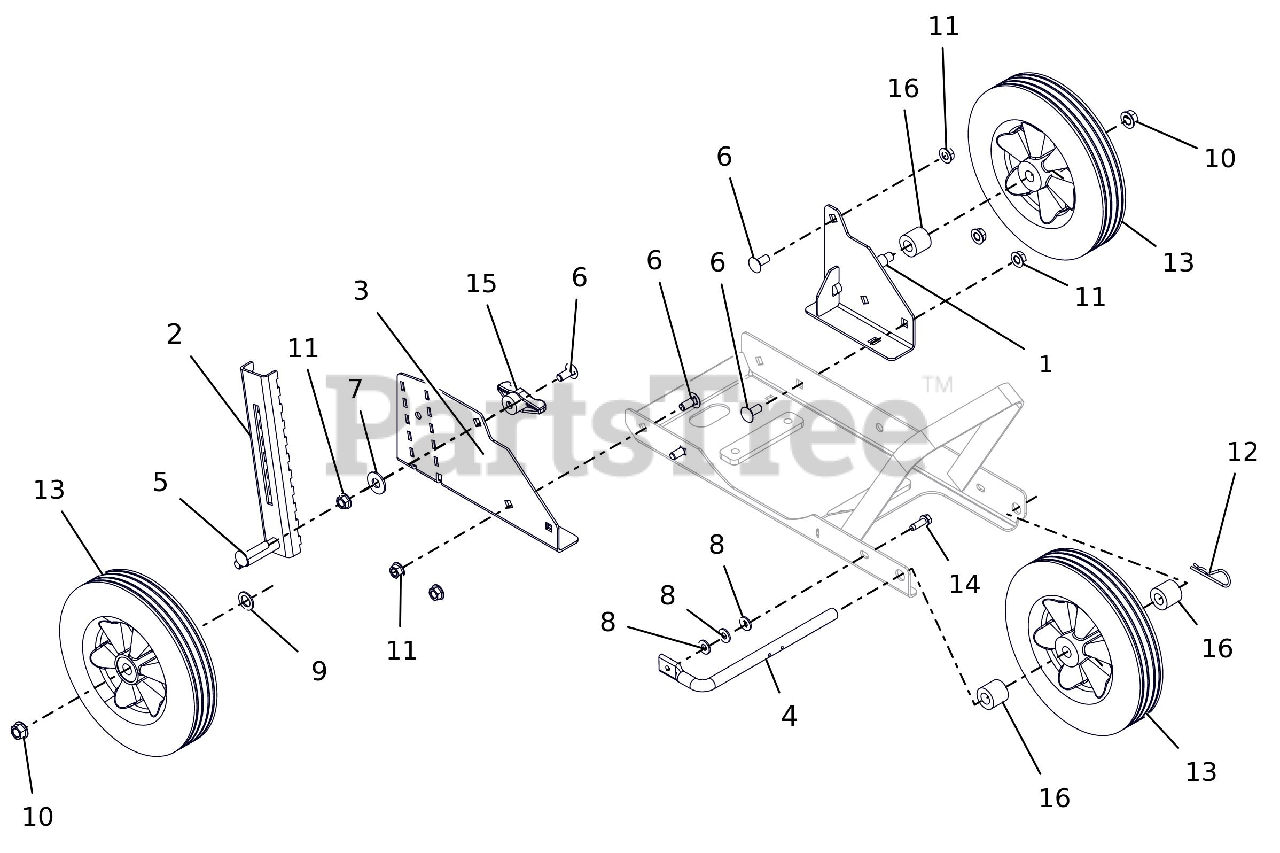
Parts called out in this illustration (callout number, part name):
1	BKT,LH WHEEL SUPPORT
2	LEG, DROP WHEEL
3	BKT, RH WHEEL SUPPORT
4	AXLE, FRONT
5	@BLT-RDHDSQNK .31-18X1.50 G5YZ
6	@BLT-RDHDSQNK .31-18X.75 G5YZ
7	@WSHR-FL-STL.438X1.00X.083 YWZ
8	@WSHR-FL-STL.281X.62X.065 YWZC
9	WSHR-FL-STL .52X.827X.062 YWZC
10	@NUT-LK-TOP-FLG .38-16 YWZC
11	@NUT-LK-TOP-FLG .31-18 YWZC
12	HAIRPIN, #7 CLIP .094X2.31 YWZ
13	WHEEL, PLASTIC-8"X1.75" .50BRG
14	SCR-TAP-PM .25-20X.75 TR YWZ
15	KNOB,WING .31-18 UNC NYL/TALC
16	SPACER .516X1.000X.875
